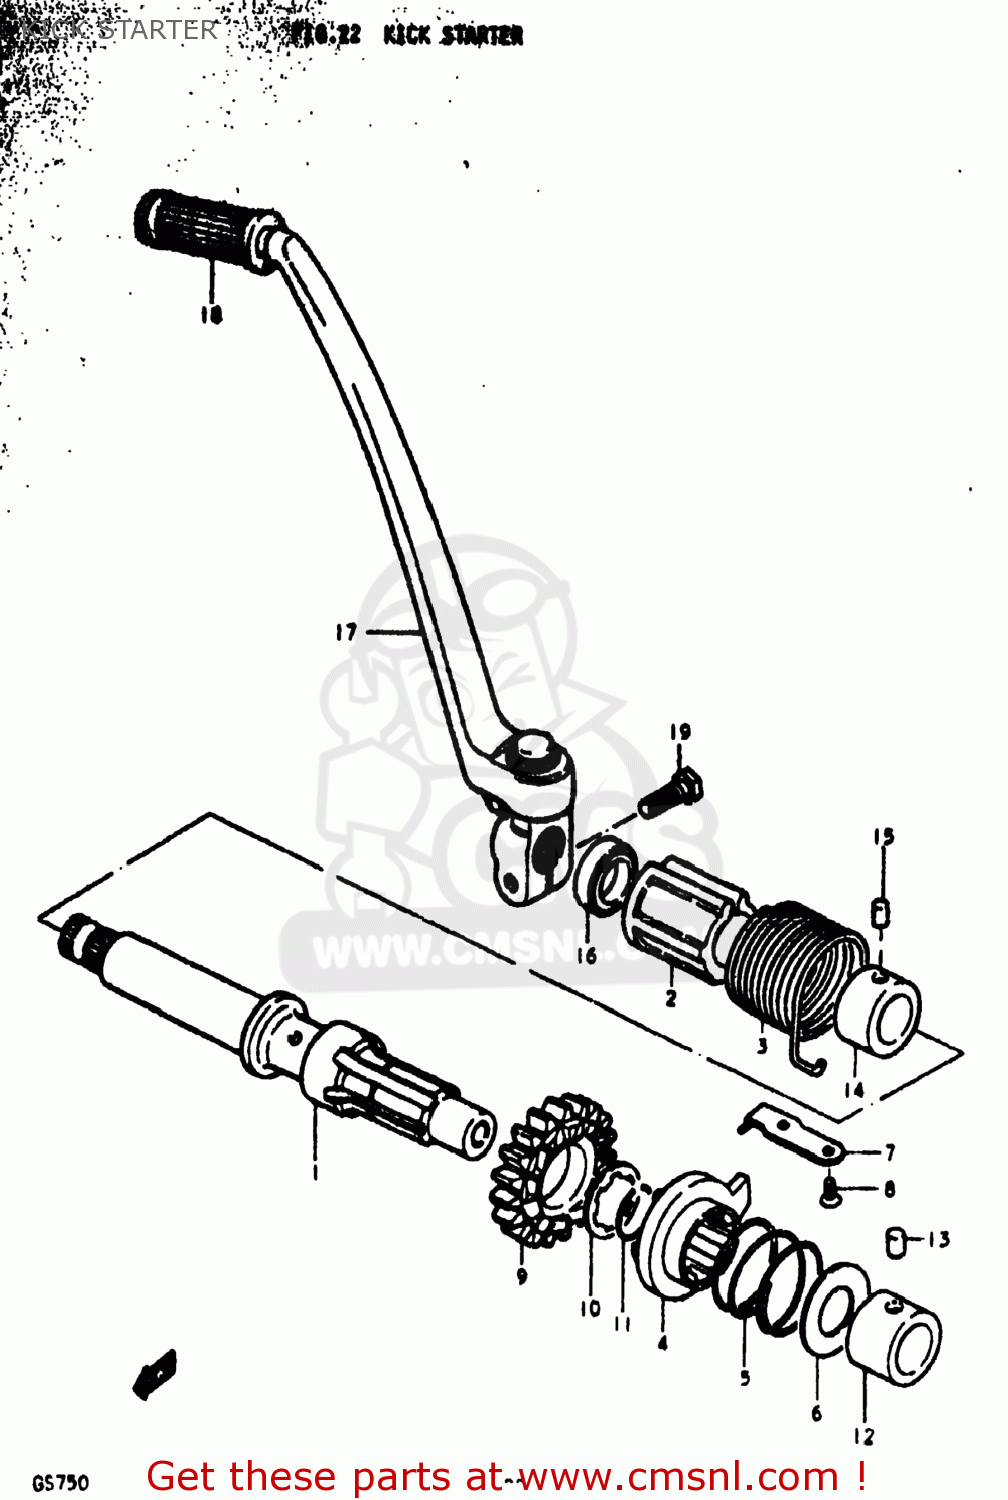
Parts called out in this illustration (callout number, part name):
1	SHAFT,KICK STARTER
2	GUIDE,KICK SHAFT SPRING
3	SPRING
4	STARTER,KICK
5	SPRING
6	WASHER
7	GUIDE,STARTING SPRING
8	SCREW
9	GEAR,KICK STARTER DRIVE
10	WASHER,LOCK
11	CIRCLIP
12	BUSHING
13	PIN
14	BUSHING
15	PIN
16	OIL SEAL
17	LEVER ASSEMBLY,KICK STARTER
18	RUBBER,KICK STARTER PEDAL
19	BOLT
